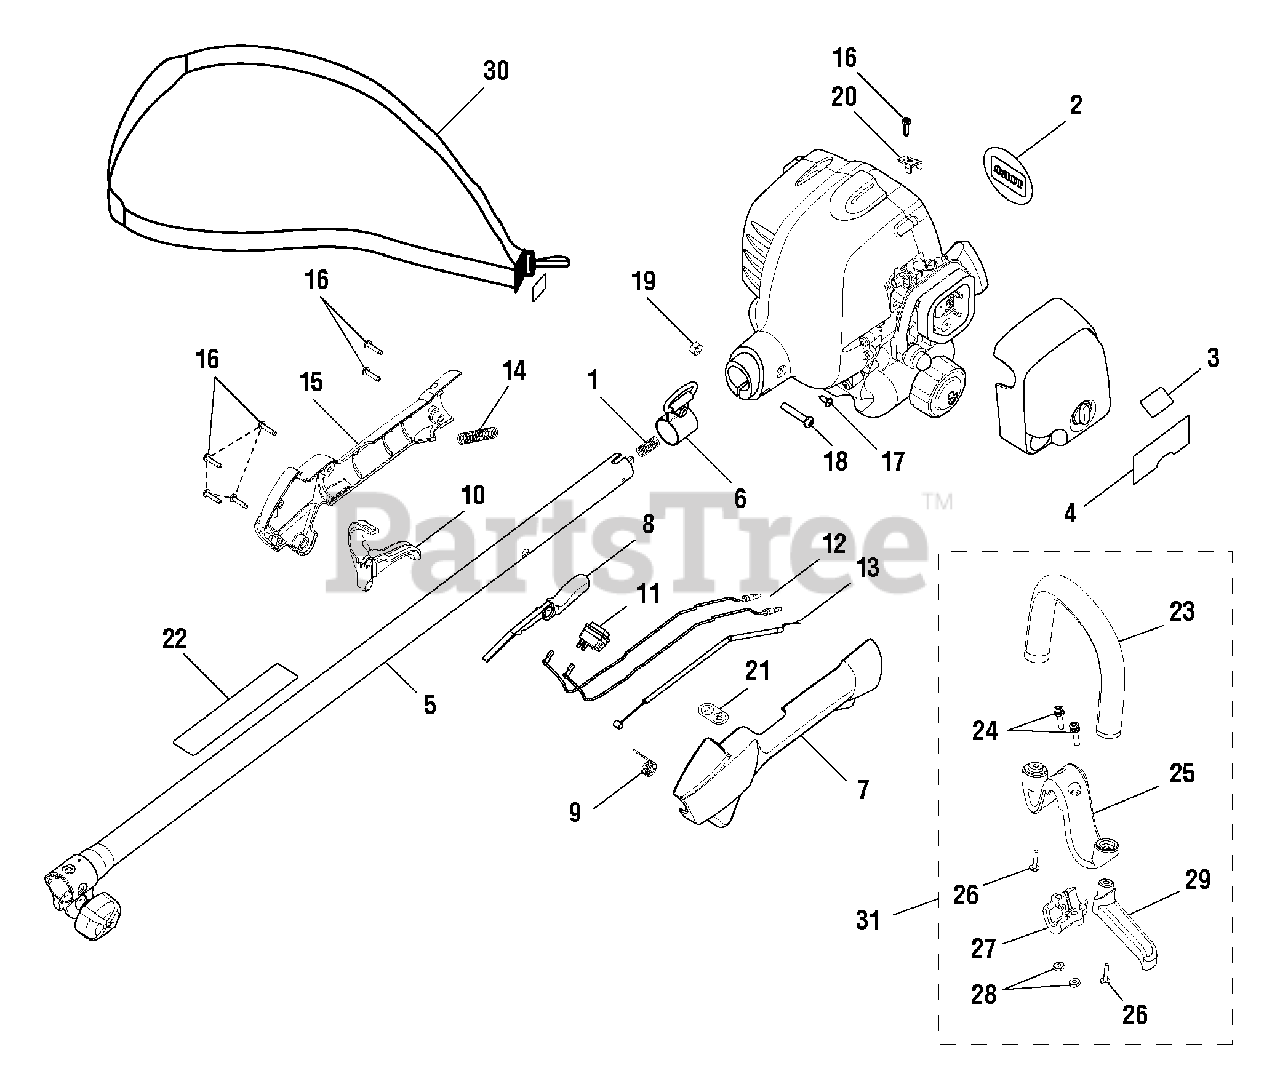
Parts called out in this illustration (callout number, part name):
1	COMPRESSION SPRING
2	LOGO PLATE
3	UPPER START LABEL
4	LOWER START LABEL
5	UPPER SHAFT ASSEMBLY
6	HANGER BRACKET
7	REAR HANDLE SUPPORT
8	LOCK-OFF BUTTON
9	TRIGGER SPRING
11	SWITCH WITH DUST SHIELD
13	CABLE, THROTTLE
14	CORRUGATED TUBE
15	REAR HANDLE COVER
16	SCREW (M4 X 16 mm)
17	SCREW (#10-14 X 1/2 in.TRI-LOBULAR)
18	SCREW (M6 X 1-30 mm)
19	HEX NUT
20	THROTTLE CABLE CLAMP
21	ON/OFF LABEL
22	WARNING LABEL
23	ASSIST HANDLE W/GRIP
24	SCREW (#12-24 X 1 in. SEMS)
25	M CLAMP
26	SLOTTED TORX SCREW
28	HEX NUT (12-24)
29	BARRIER BAR
30	HARNESS ASM. W/LABEL
31	ASSIST HANDLE W/BARRIER
